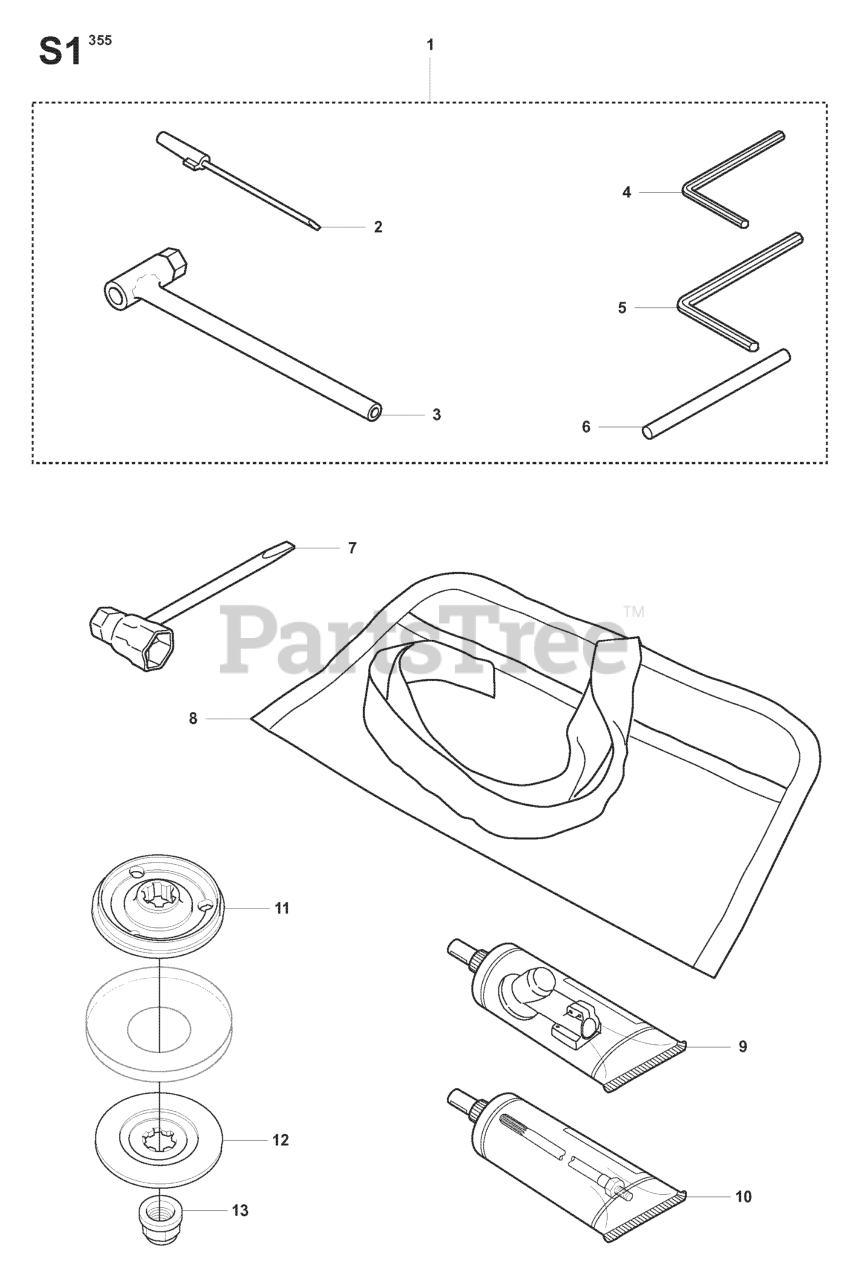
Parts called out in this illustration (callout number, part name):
1	ACCESORY BAG
1	RP ACCESSORY BAG
2	SCREWDRIVER
4	L-KEY WRENCH
5	KEY
6	LOCKING PIN
7	COMBI TOOL
9	BEVEL GEAR GREASE
10	DRIVE SHAFT GREASE (200 G)
11	CARRIER
12	SUPPORT FLANGE
13	BLADE NUT
